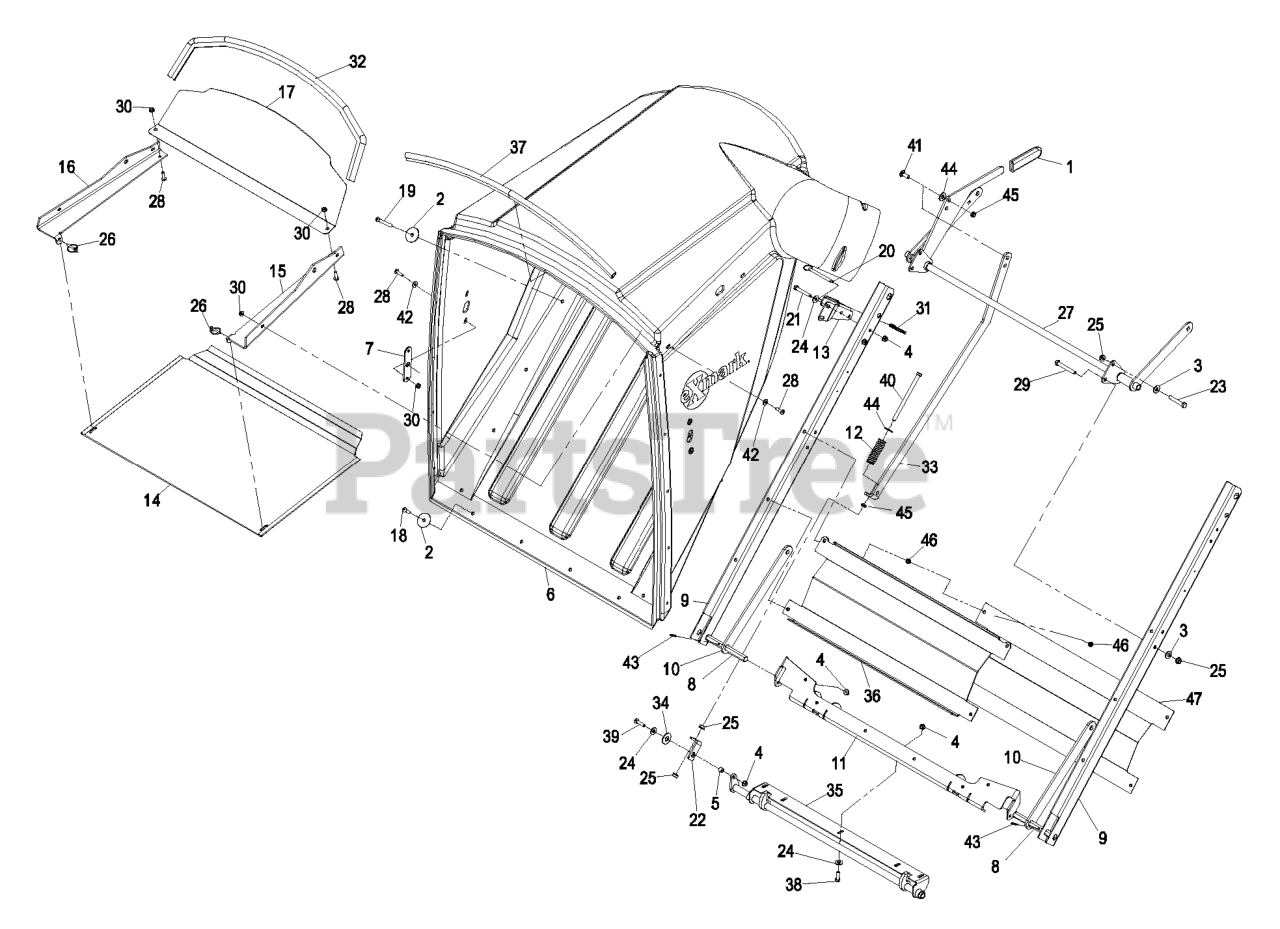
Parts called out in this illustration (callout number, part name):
1	GRIP-LEVER
3	WASHER-BELLEVILLE
4	NUT-HF, NI
5	BUSHING, LOCATOR
6	HOPPER,FR 12 BUSHEL
7	PLATE,FR LWR PVT BACKING
8	SHAFT,.625 HEX
10	LINK,FR HOPPER PIVOT
12	SPRING-COMPRESSION
13	BRACKET,FR HNDL STORAGE
14	SCREEN,FR HOPPER
16	ANGLE,LH FR SCRN SUPT
17	BAFFLE,FR HOPPER SCREEN
18	SCREW-HSBH
19	SCREW,HSPH
20	PIN-HITCH, COTTERLESS
21	SCREW-HH
22	LINK,BRAKE (PLATED)
23	SCREW-HH
24	WASHER-FLAT
25	NUT-HHF, WHIZ
26	PIN-KLIK
28	SCREW-TTH
29	SCREW-HH
31	STRIP-SEAL
32	SEAL,TRIM 38.00
33	LINK,FRUVD LATCH
34	WASHER-FLAT
35	WLD,FRUVD LATCH
36	SHIELD,FRUVD INNER HEAT
37	SEAL,SIDE TRIM 34.50 X .1
38	SCREW-HH
39	SCREW-HH
40	BOLT-TAP, HH
41	SCREW-CARR
42	WASHER-FLAT
43	PIN-SPRING
44	WASHER-FLAT
46	NUT-LOCK, NI
47	SHIELD,FRUVD OUTER HEAT
48	Asm, Latch Link
